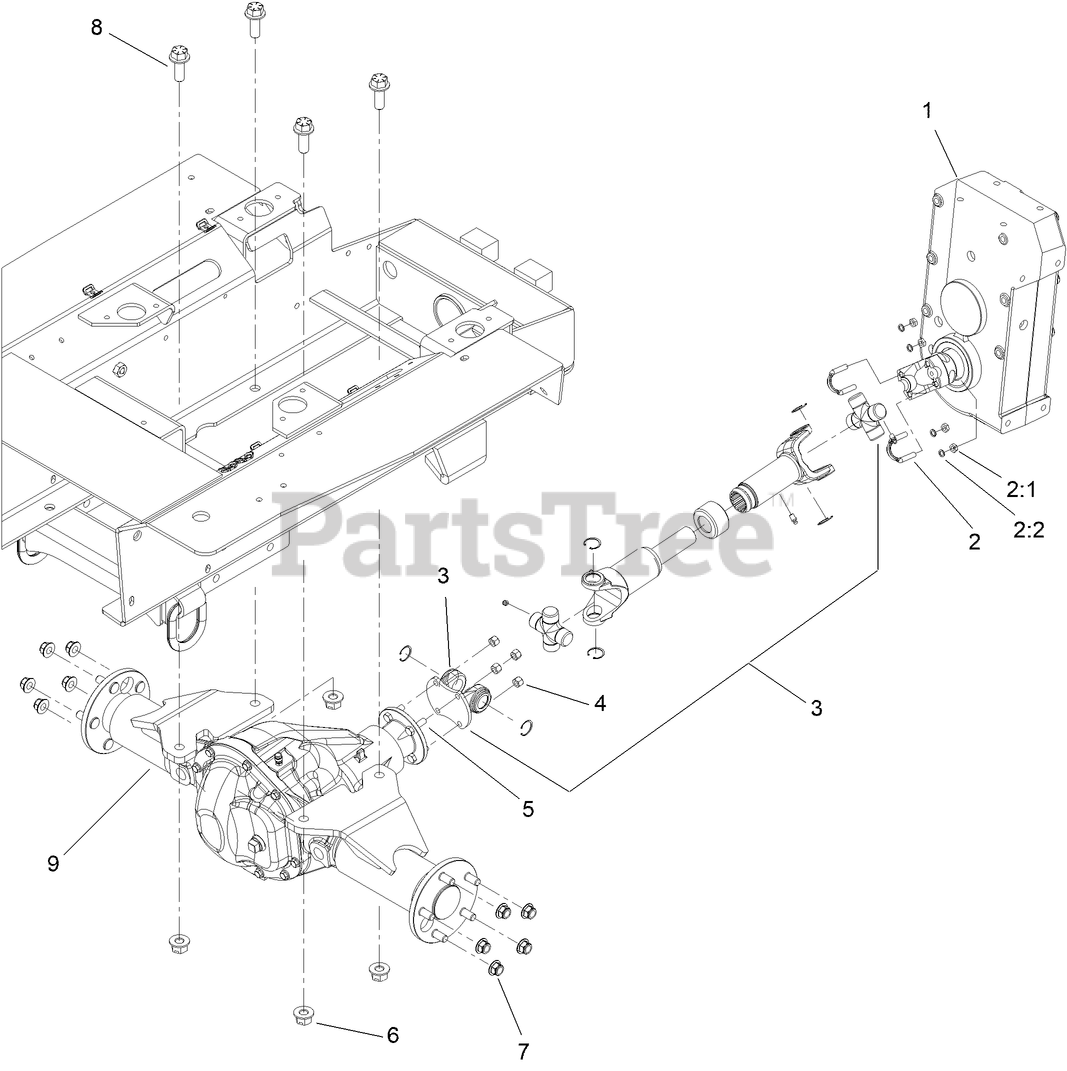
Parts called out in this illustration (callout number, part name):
1	TRANSMISSION ASM
2	BOLT-U (2 PER PACK)
2:1	NUT-HEX
2:2	WASHER-LOCK
3	DRIVE SHAFT ASM
4	NUT-HEX
5	SCREW-HH
6	FLG LOCKNUT (5/8-NC, GR G)
7	NUT-HHF
8	FLG BLT (5/8-NC X 1-3/4", GR 8)
9	DANA 44 ASSEMBLY
